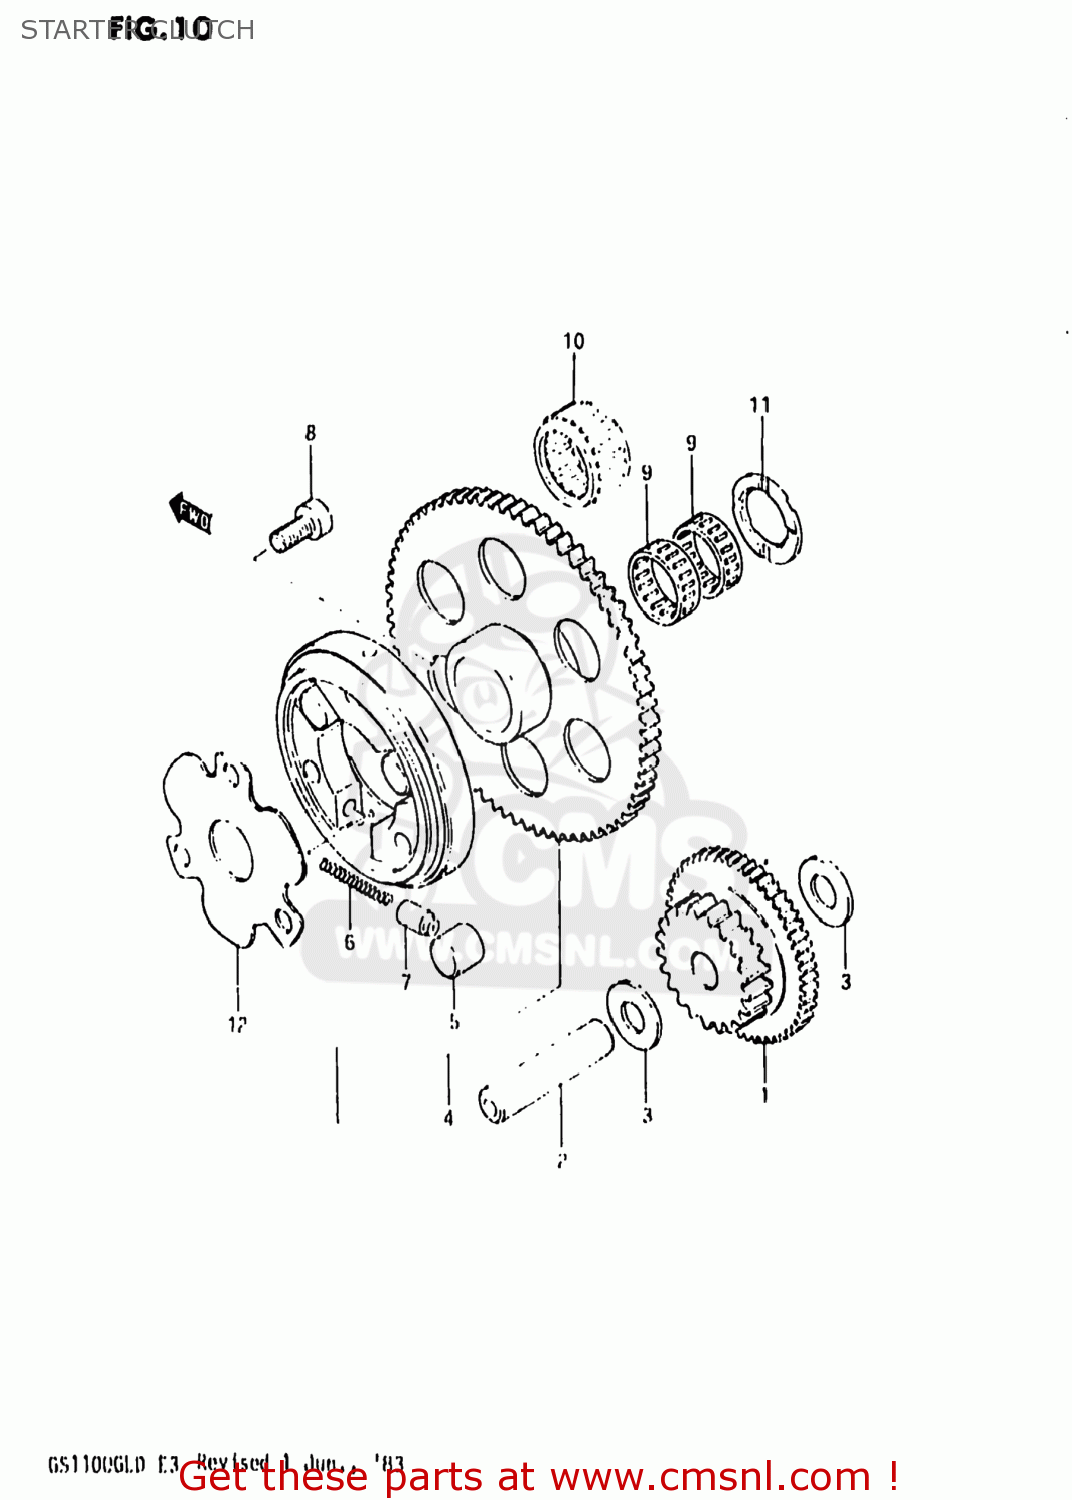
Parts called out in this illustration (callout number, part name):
1	GEAR,STARTER IDLE
2	PIN(7.4X13X56)
3	WASHER(13.3X25X0.85)
4	CLUTCH SET,STARTER
5	PIN(14X13)
6	SPRING
7	PIECE,PUSH
8	BOLT
9	BEARING
10	ROLLER BEARING (25X31X2
11	WASHER(25X38X2.5)
12	SHIM,STARTER CLUTCH HUB
